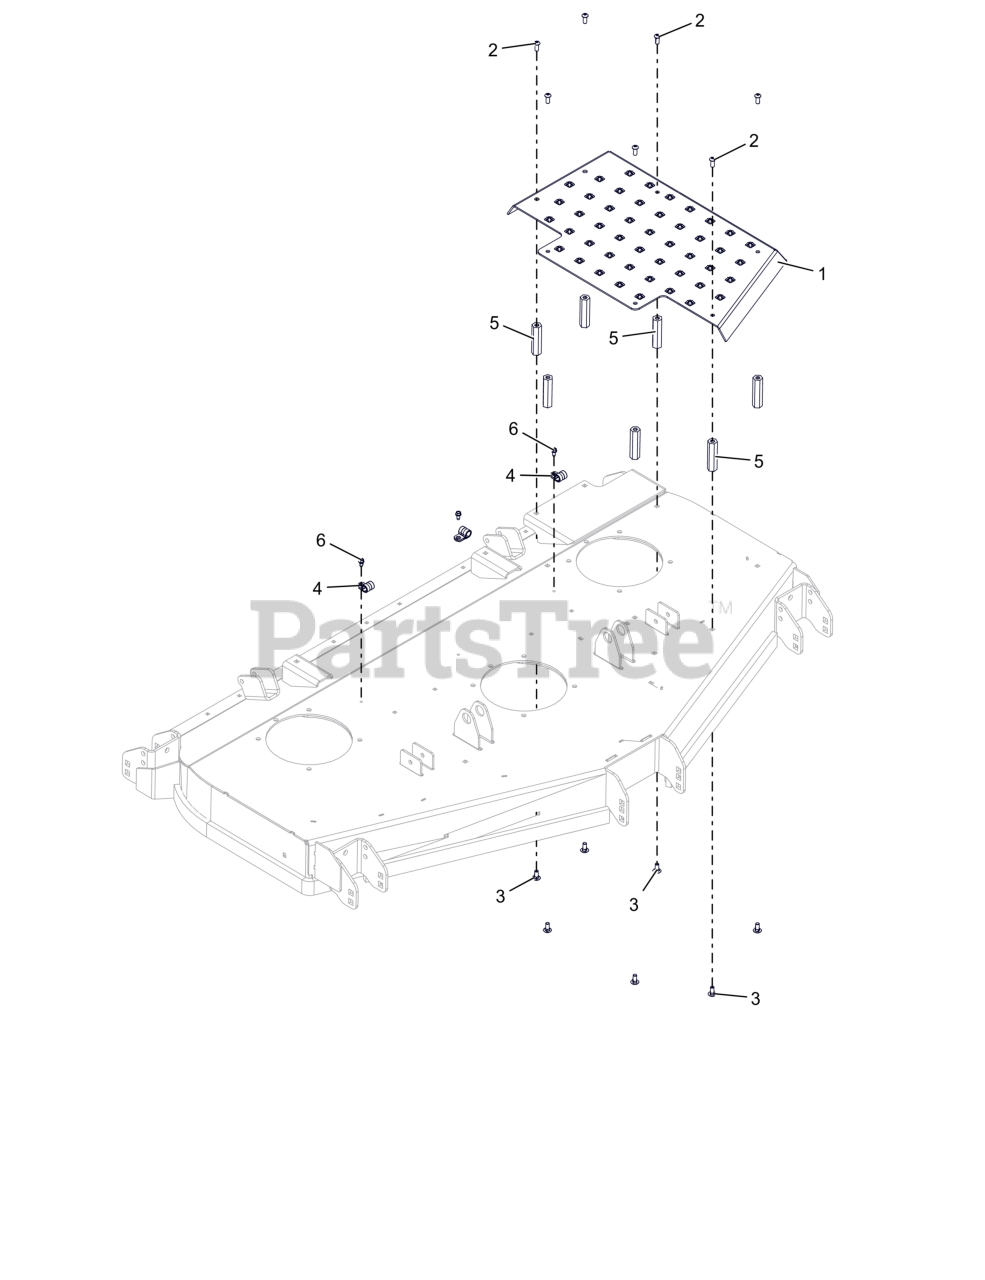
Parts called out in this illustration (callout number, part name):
1	PLATFORM, WLDMT 60 RD DECK STEP (RED)
2	SCR-SKH .31-18X.75 BTNHD YWZC
3	BTL,RHSN .313-18 X 0.75 G5 ZCC LT
4	CLAMP, CUSHIONED STEEL
5	NUT, COUPLING .31-18 X 3.00
6	SCR-TAP .25-20X.50 HWH ZCC
